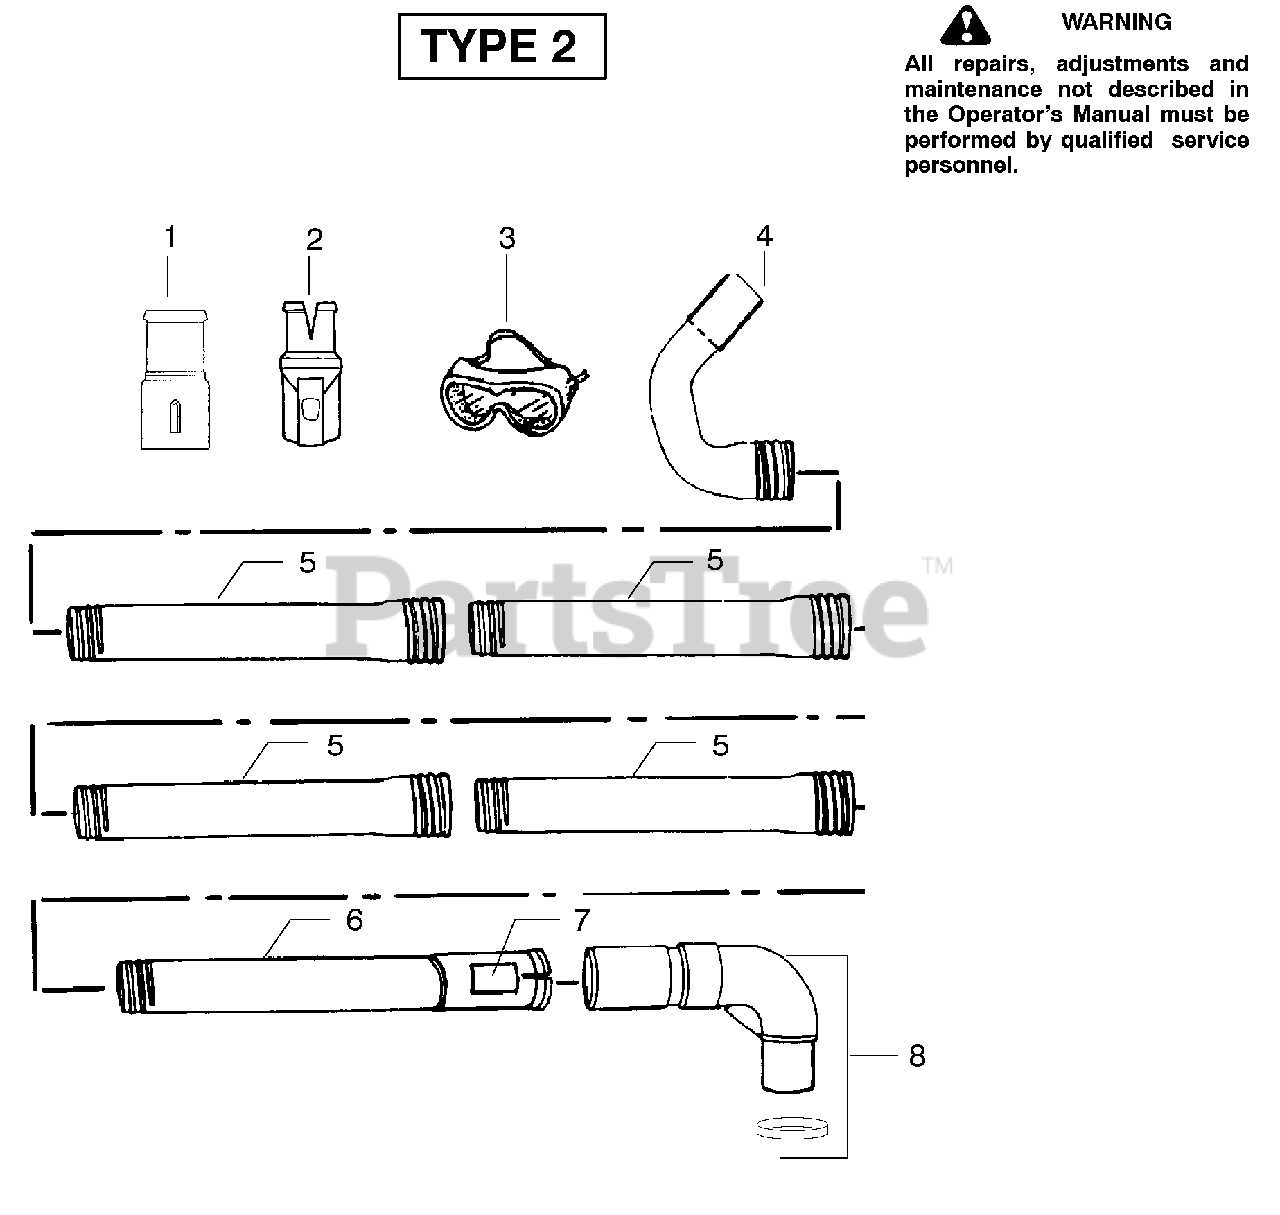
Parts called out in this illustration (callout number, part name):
2	Adapter-Gutter Kit
3	Goggles
5	Tube-Extension
7	Decal-Warning
8	Elbow&Spacer Ring
